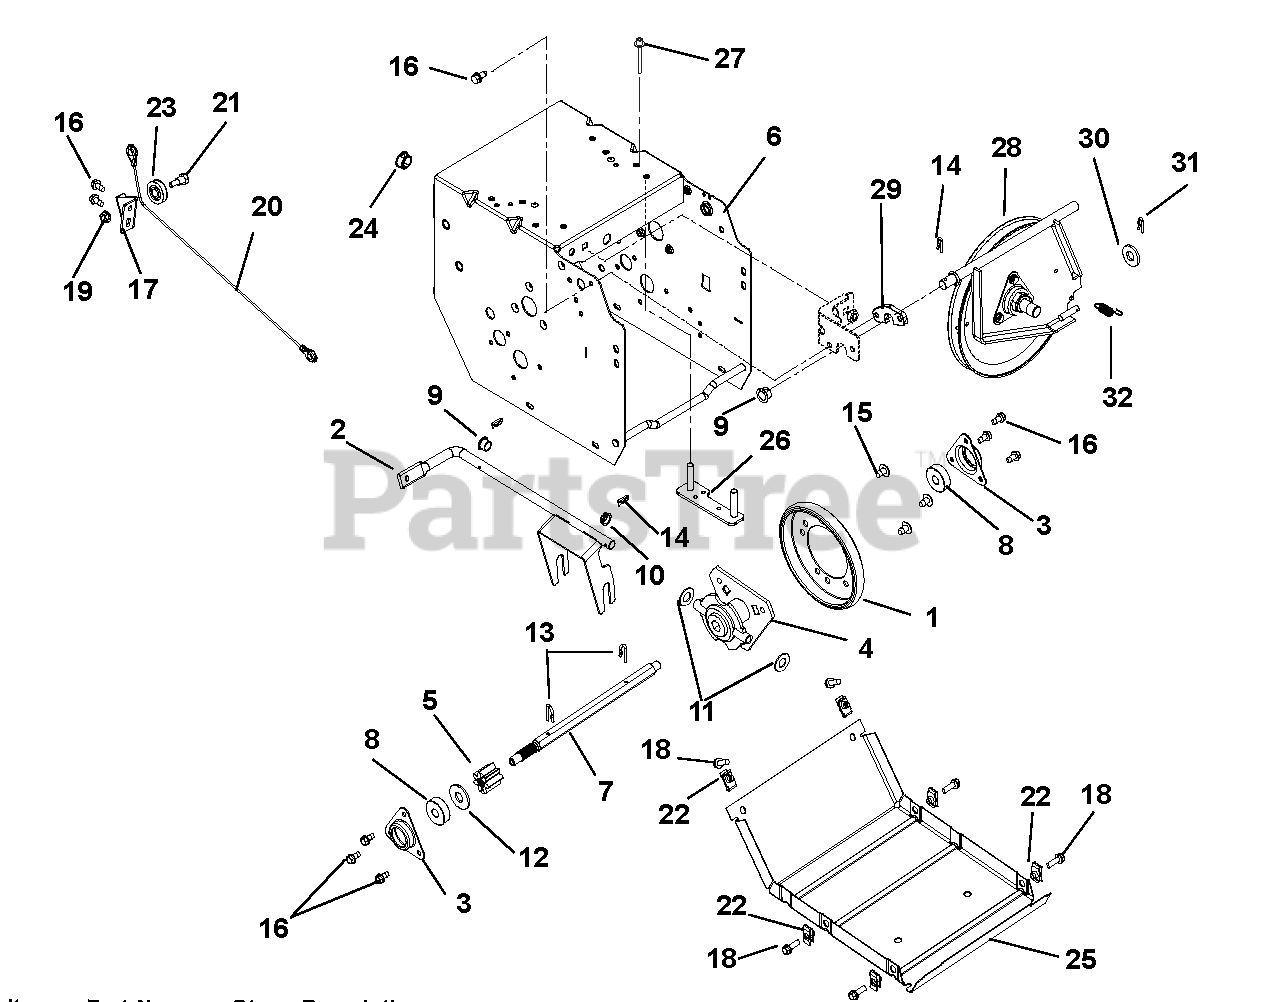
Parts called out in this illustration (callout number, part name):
1	FRICTION, DISC
2	WELDMENT, SHIFT FORK
3	FLANGE, BEARING
4	CARRIER, DRIVE DISK
5	GEAR, PINION, 7 TOOTH W/SPLINE
6	FRAME, 920/921
7	SHAFT, HEX W/SPLINE
8	BRG-BALL .437X1.375X.437
9	BUSHING, POLYLINER-.50 SPLIT
10	BUSHING, POLYLINER-.50 SNAPIN
11	WSHR-FL-STL .505X1.00X.062YWZC
12	@WSHR-FL-STL.563X1.38X.109YWZC
13	PIN, SPRING CLIP
14	CLIP, SPRING
15	SCR-TAP SERRDHDTX .31-18X.50BP
16	SCR-TAP .25-20X.50 HWH TR YWZ
17	BRACKET, CABLE PULLEY
18	BLT-HEX .25-20X.75 HWH YZ GR5
19	@NUT-LK-TOP-FLG .25-20 YWZC
20	CABLE, LOWER TRACTION (CMPCT)
21	BOLT, SHLDR-.375X.375X.25-20
22	NUT-RTNR .25-20X.56
23	PULLEY, CABLE
24	PLUG, HOLE - .875" NYLON
25	COVER, BOTTOM
26	STRAP, ENGINE BOLT-WELDMENT
27	RVT-POP .187 YZ
28	PLATE, SWING - ASSEMBLY
29	SPACER, SWING GATE
30	@WSHR-FL-STL.344X.688X.065YWZC
31	PIN-HAIR INT .08X.18X1.18 YWZC
32	SPRING, EXT. .043X.438X1.64
